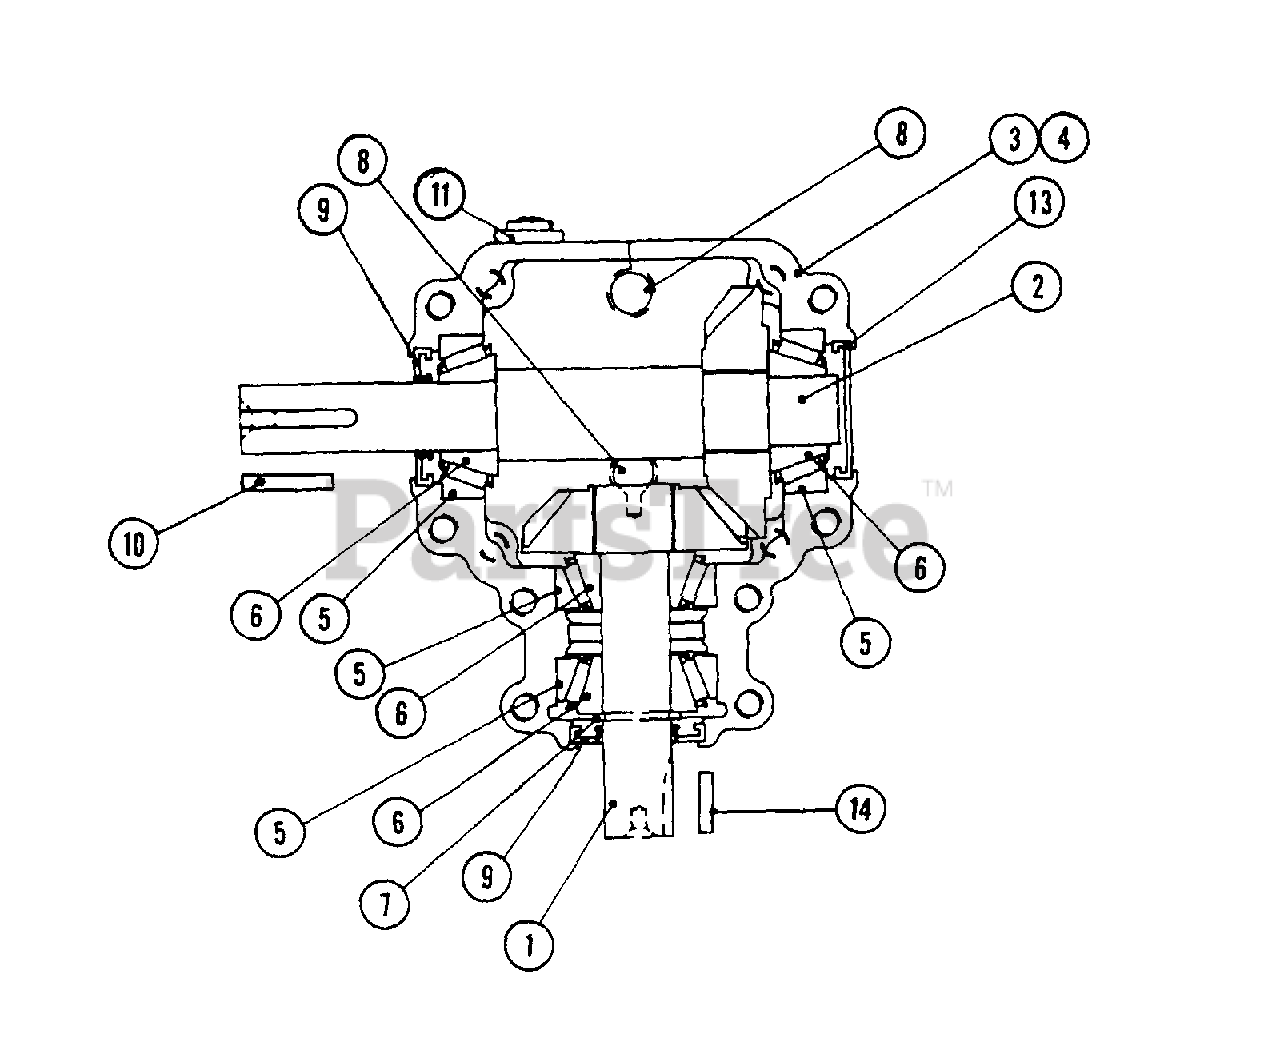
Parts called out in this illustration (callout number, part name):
1	SHAFT - pinion, with gear
2	SHAFT - cross, with gear
3	HOUSING - with tapped holes
5	CUP - bearing
6	CONE - bearing
7	RING - retaining
8	PLUG - pipe 1/4"
10	KEY - 3/16" x 1" input shaft
11	PIPE - vent
13	CAP - end
14	KEY - 3/16" x 5/8" output shaft
